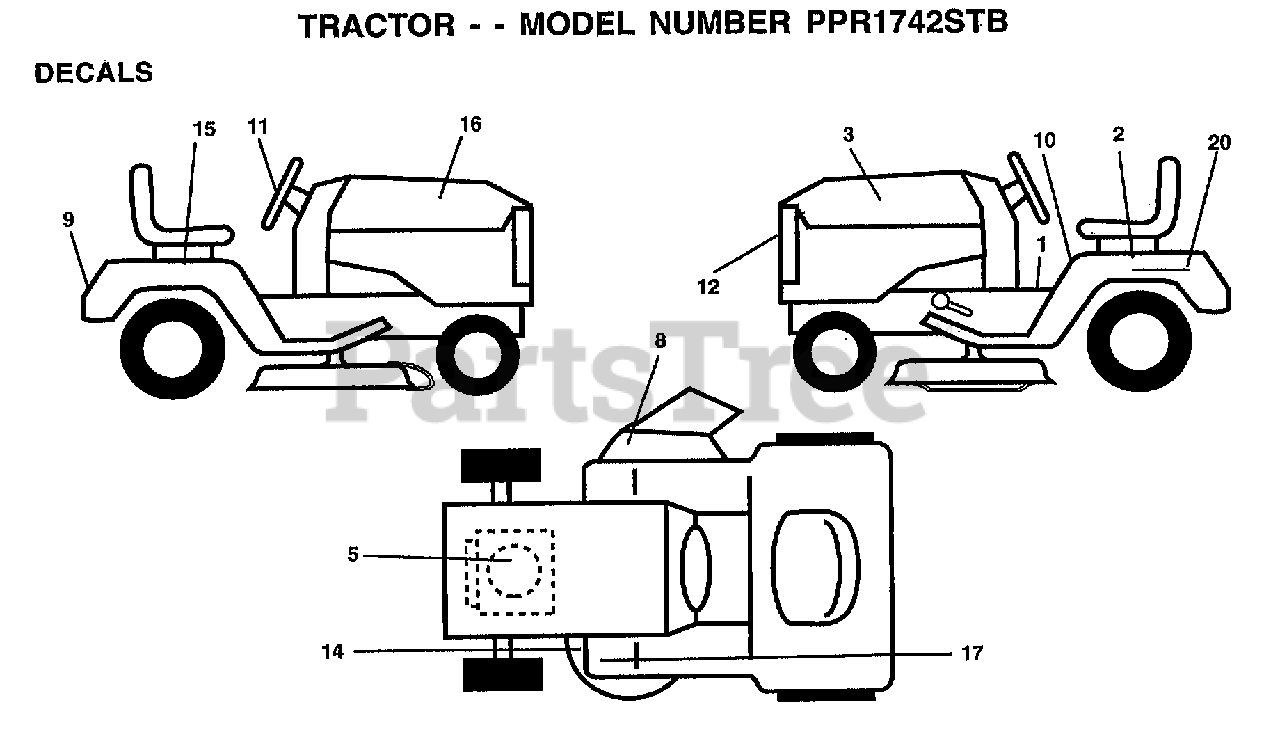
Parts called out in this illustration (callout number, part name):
1	"DECAL.OPER,SDL"
2	DECAL.FENDER.SIDE.LH
3	DECAL.HOOD.LH
5	DECAL, HP ENGINE
8	"DECAL, WARNING"
9	DECAL.FENDER.LOGO
10	DECAL.CAUT.ENG/FR
11	DECAL.INS.WHL.STRG
12	DECAL.GRILLE.
14	"DECAL-SCHEM,BELT"
15	DECAL.FENDER.SIDE.RH
16	DECAL.HOOD.RH
17	DECAL T
20	DECAL.BATRY.3-3908
